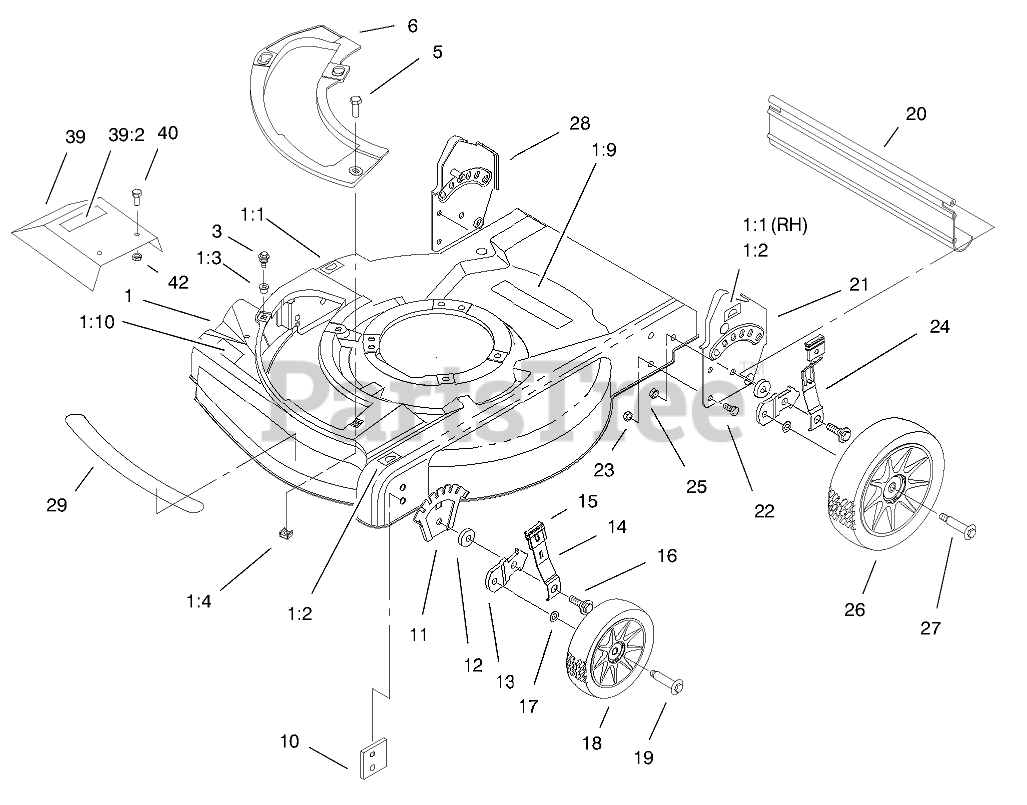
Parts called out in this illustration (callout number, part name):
1	HOUSING - HP
1:1	DECAL-HOC, RH
1:2	DECAL-HOC, LH
1:3	NUT-CLIP
1:4	NUT-CAGE
1:9	DECAL-DANGER
1:10	DECAL - WARNING
3	SCREW-SEMS
5	SCREW-HWH
6	PLATE-OPENING, CHUTE
10	PLATE-BAFFLE
11	Plate H.O.C.
12	WASHER
13	Bracket-Wheel Height Adj
14	ARM-FRONT SPRING
15	KNOB-LEVER, HEIGHT ADJUSTMENT
16	BOLT-SHOULDER
17	WASHER
18	WHEEL AND TIRE ASM
19	BOLT-SHOULDER
20	SHIELD-TRAILING
21	LH HANDLE BRACKET ASM
22	SCREW-HH
23	NUT-LOCK, NI
24	REAR SPRING ARM ASM
25	NUT-LOCK, NI
26	WHEEL ASM
27	BOLT-SHOULDER
28	RH HANDLE BRACKET ASM
29	DECAL - DECK
39	GUARD PLATE ASM
39:2	DECAL - WARNING
40	SCREW-HWH
42	NUT-LOCK, NI
